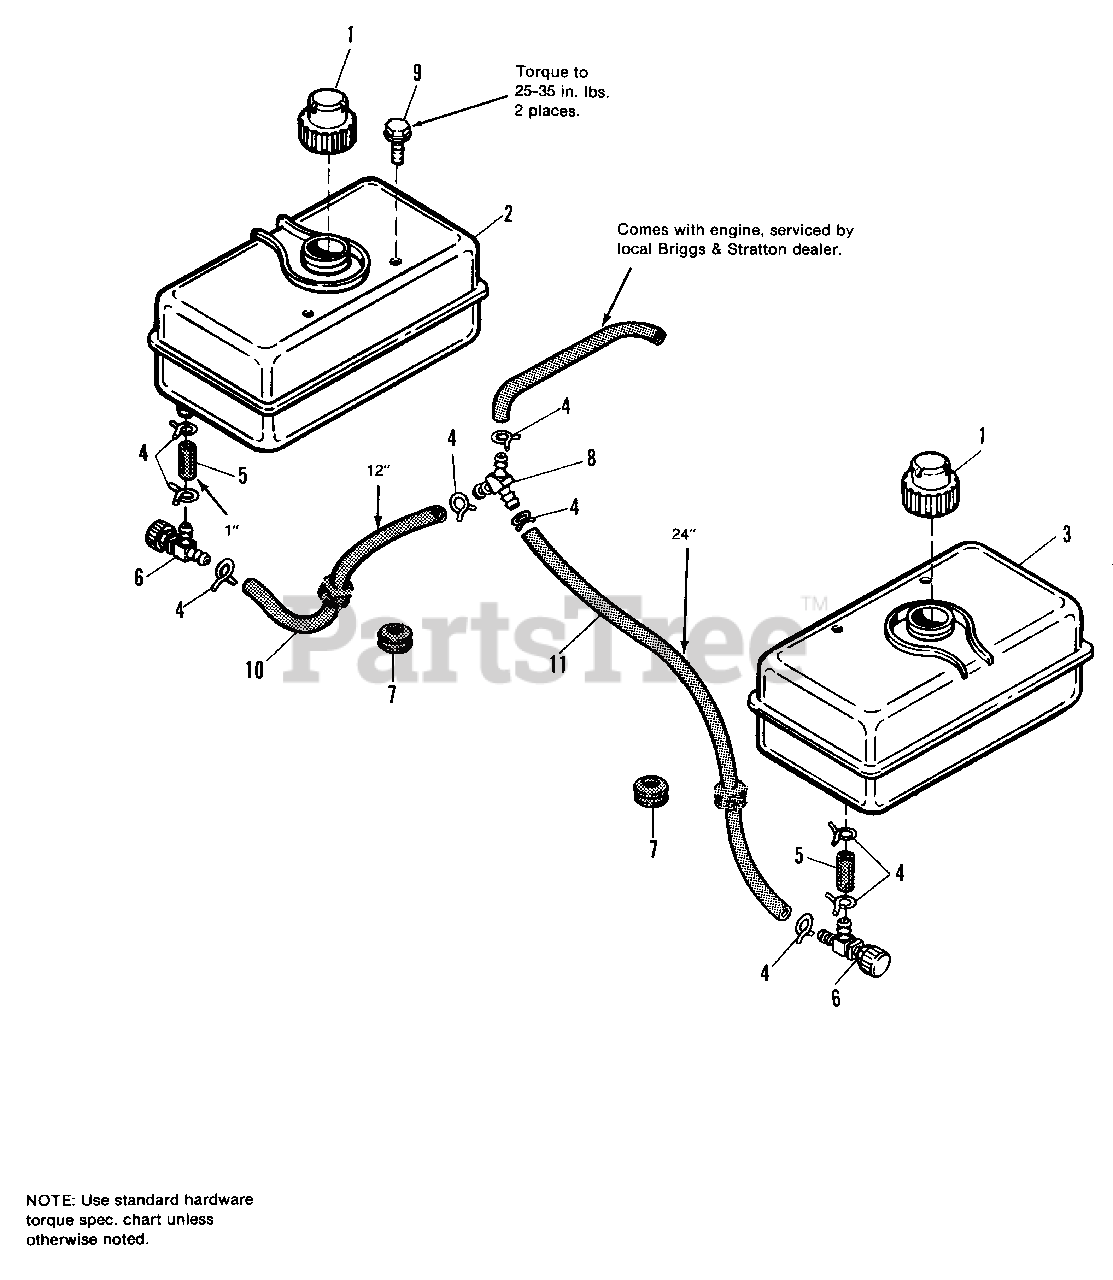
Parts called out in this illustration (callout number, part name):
1	CAP, Fuel Tank
2	TANK, Fuel (R.H.)(Incl. Qty. 1, Ref. No. 1)
3	TANK, Fuel (L.H.)(Incl. Qty. 1, Ref. No. 1)
4	CLAMP, Hose
6	VALVE, Shutoff
8	FITTING, Tee
9	SCREW, Special
10	HOSE, Fuel
11	HOSE, Fuel
